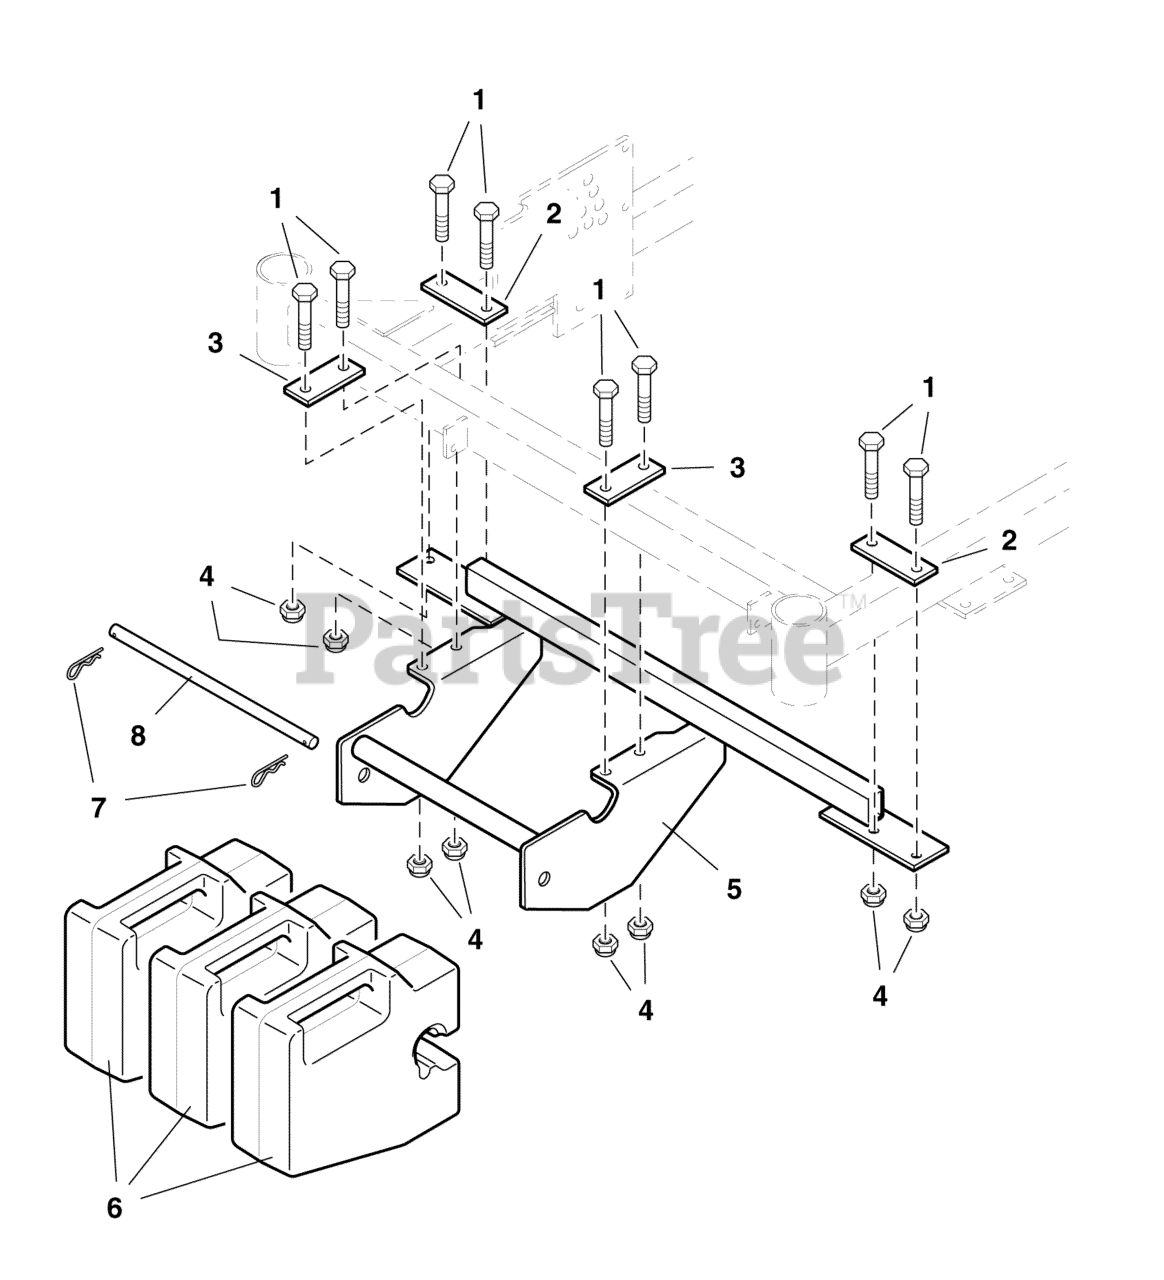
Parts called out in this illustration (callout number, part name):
1	BOLT, 3/8-16 X 3" GD5 CZ
2	BAR CLAMP, SIDE TUBE
3	PLATE, BRACE-LOWER
4	NUT, 3/8-16 HEX NYLON LOCK
5	WEIGHT MOUNT WELDMENT, 3-BAG
6	WEIGHT-QUICK ATTACH 50LB SUITCASE PAINTED
7	PIN, HAIR, .0915 X 1-7/8
8	ROD, WEIGHT RETAINING
